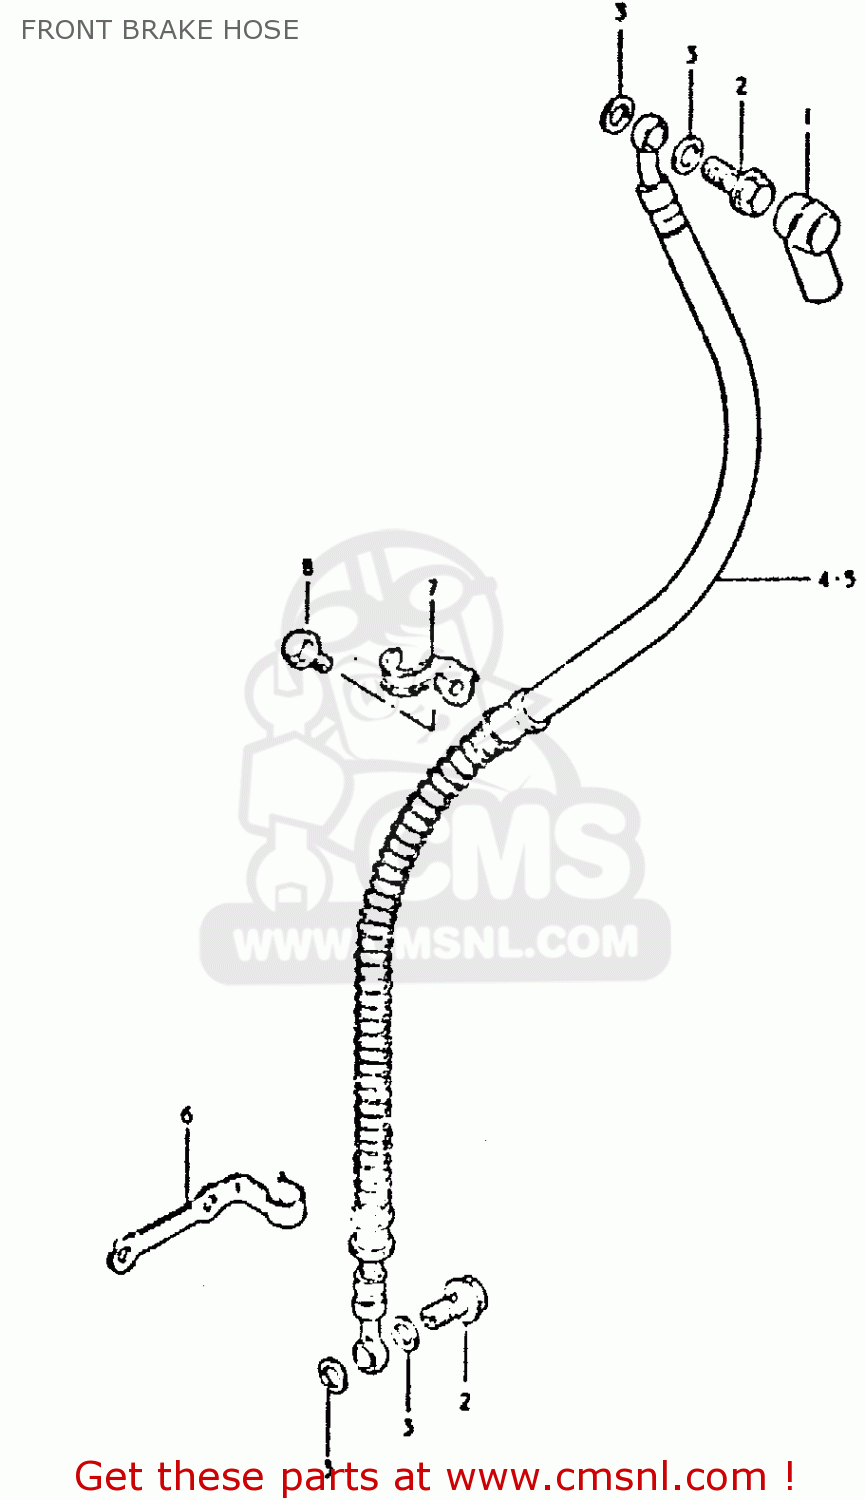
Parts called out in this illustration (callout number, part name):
1	BOOT,MASTER CYLINDER
2	BOLT,UNION
3	WASHER
4	HOSE,FRONT BRAKE
5	HOSE,FRONT BRAKE
6	GUIDE,BRAKE HOSE NO.2
7	GUIDE,BRAKE HOSE NO.3
8	BOLT
